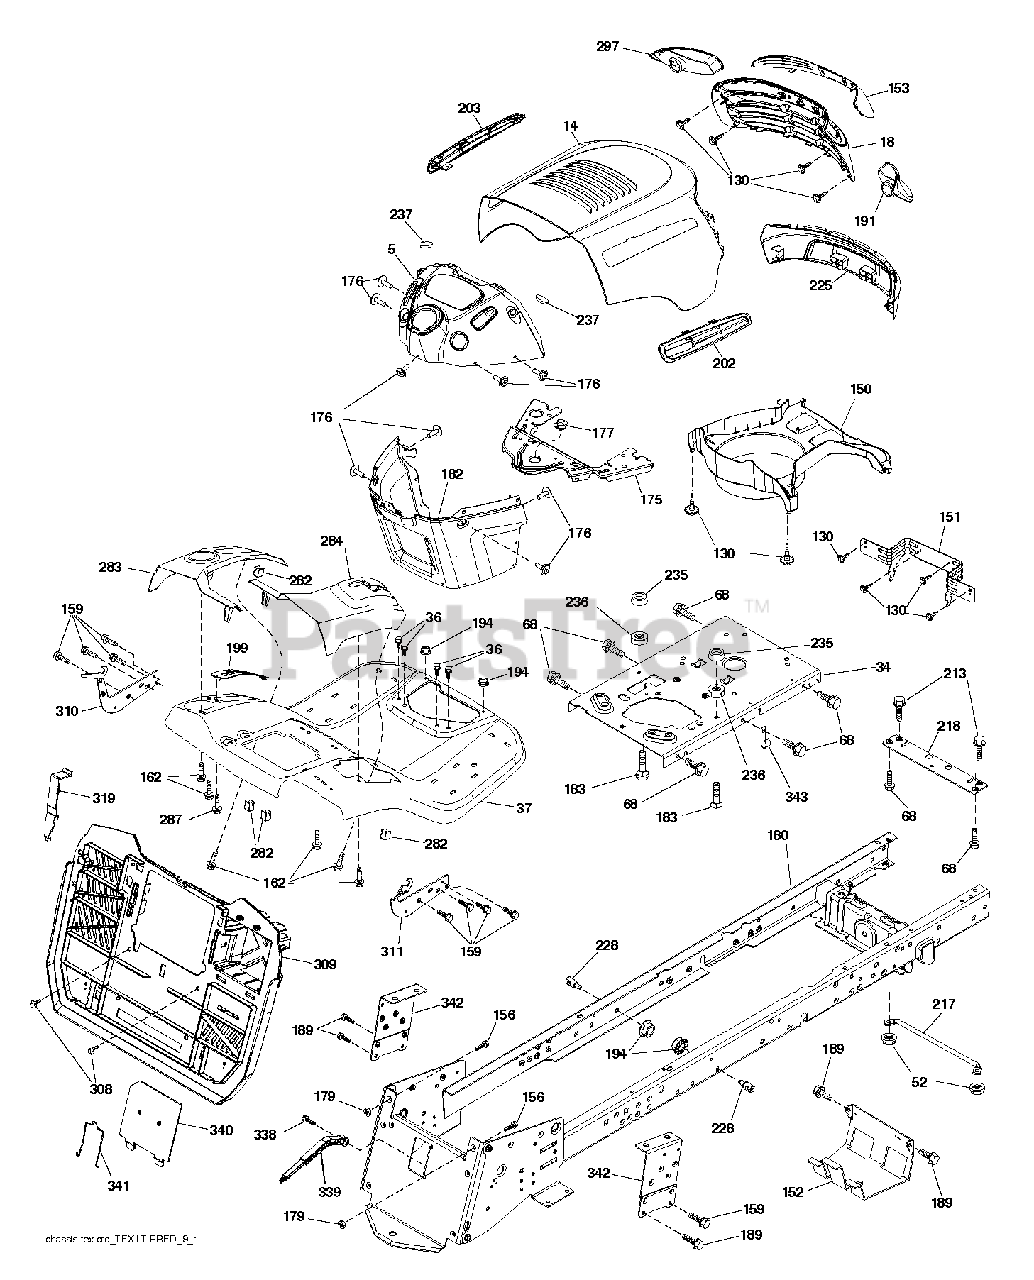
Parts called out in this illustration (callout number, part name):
36	SCREW 5/16"
52	LOCKNUT
130	SCREW.#10 X 0.750.BOS THREAD
151	BRACKET.PIVOT.ALPHA.LT
152	SHIELD BROWNING
153	LENS.PREDATOR.LT
156	BOLT
159	SCREW, 3/8-16X3/4
162	SCREW.HI-LO.CONSOLE
175	CROSSMEMBER
176	SCREW.#10-24X5/8.RN.QU
177	BUSHING STEERING
182	DASH.LWER.PREDATOR/HUSQ.LT
183	BOLT.5/16-18X1-1/4 FULL THD
189	SCREW
191	INSERT.REFLECT.PREDATOR.LT.RH
194	NUT LOCK HEX FLANGE 5/16-18
213	BOLT
217	ROD.PIVOT.HOOD
218	X-PIECE.HOOD.STOP.NON/
228	STUD.FASTNER.W/ANTI-ROTATE
235	SPACER FENDER
236	NUT.CENTERLOCK.5/16-
237	PLUG.MOUNT.CARGO.BLK
282	CLIP.RETAINER.CONSOLE.LT.HUSQ
297	REFLECTOR.INSERT.PRED.LH.LT
308	BOLT, 5/16-18 X 1 3/4
